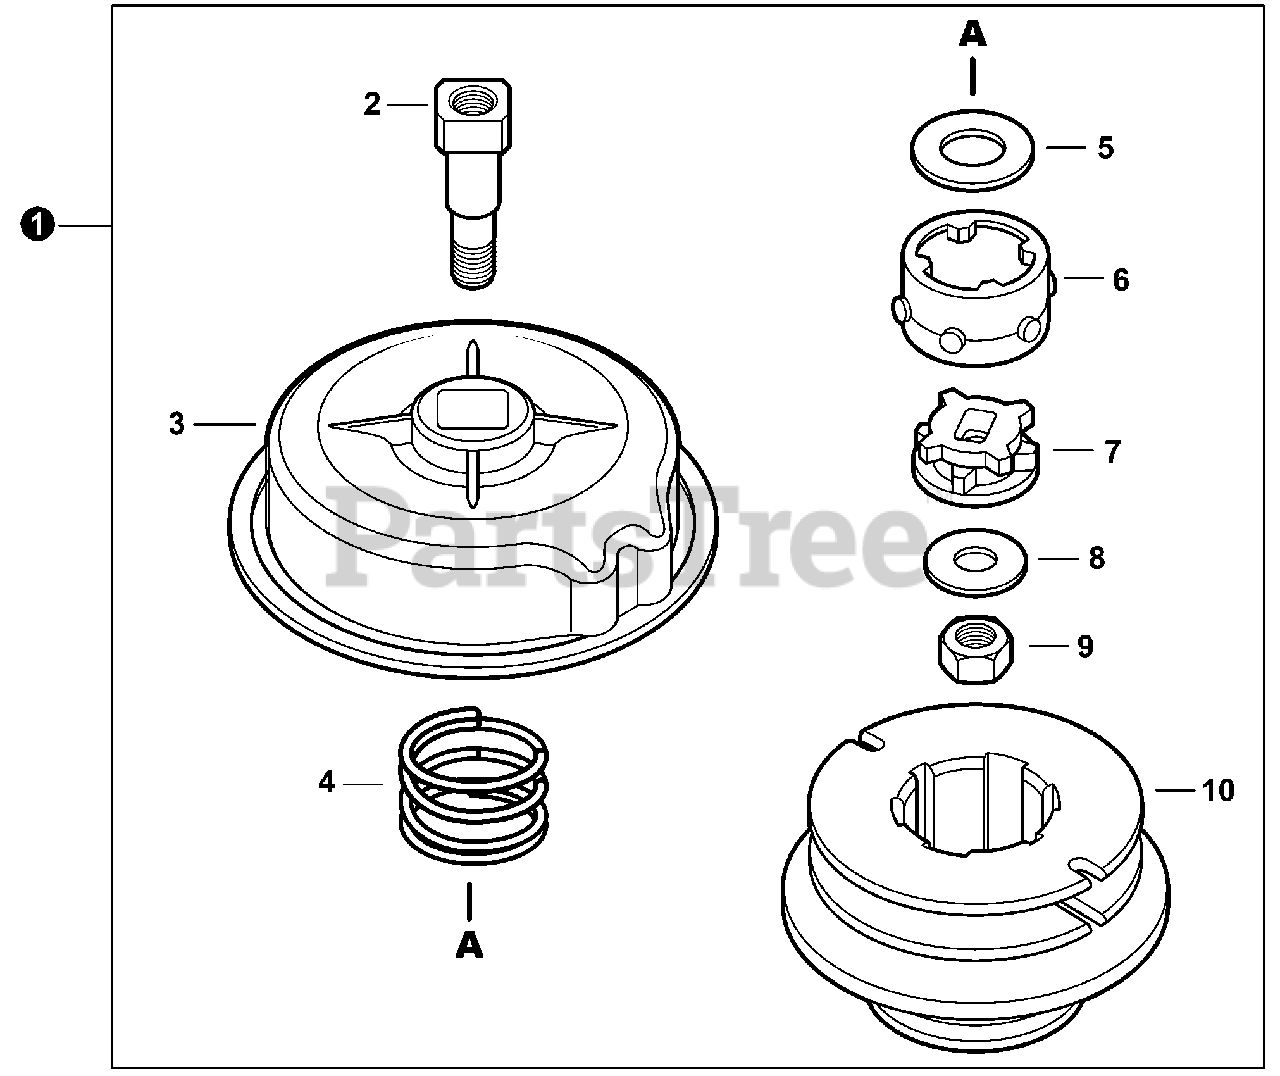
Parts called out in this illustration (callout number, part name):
1	TRIMMER HEAD, SRM ECHOMATIC® PROT
2	BOLT, SHAFT 10 MM
3	HOUSING
5	WASHER, FLAT
6	CAM, OUTER
7	CAM, INNER
8	WASHER, FLAT
9	NUT, LOCK
